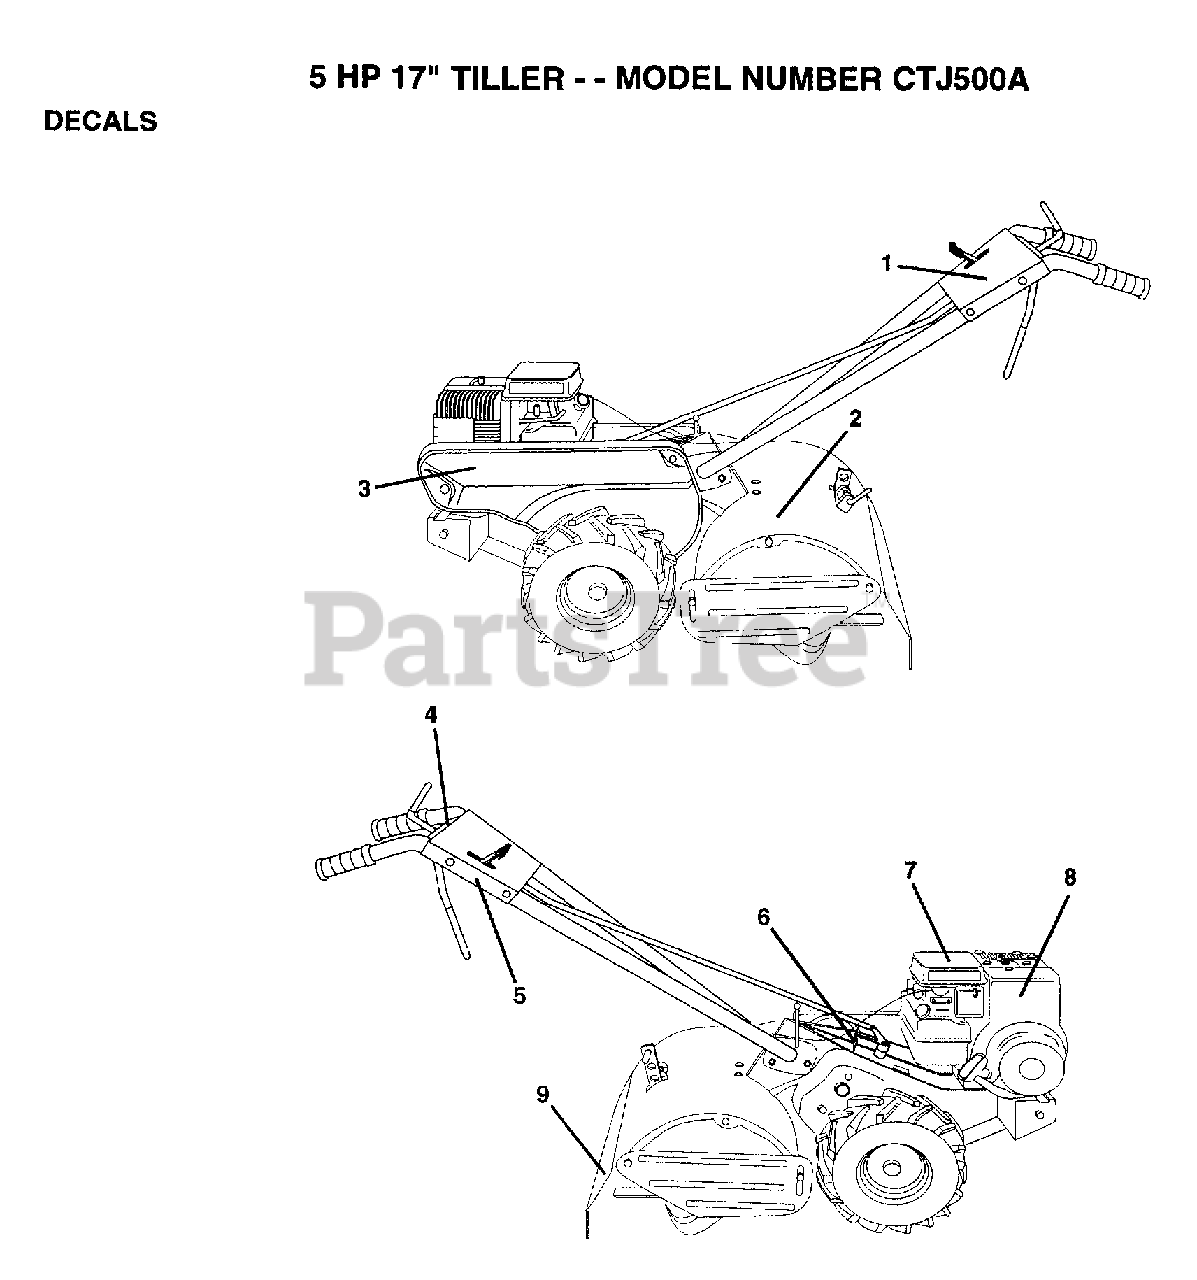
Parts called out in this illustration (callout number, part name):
1	DECAL.CTL.PANEL
2	"MANUAL, FRE"
3	DECAL.GUARD.BELT
5	DECAL TI
6	DECAL CRT
9	DECAL TI
